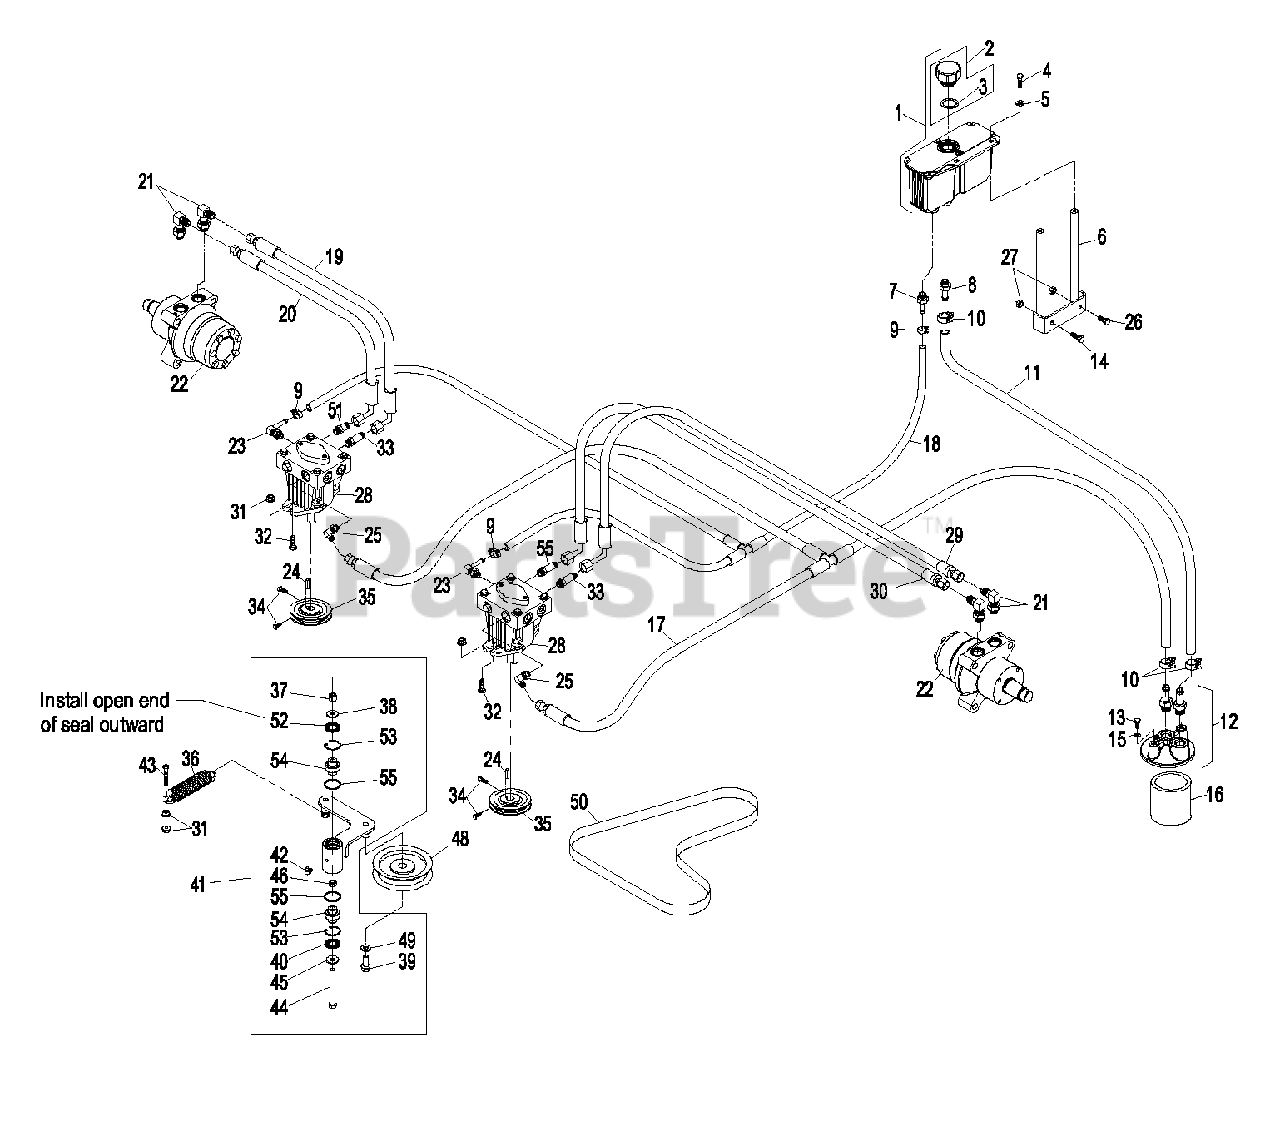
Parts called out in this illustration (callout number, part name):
1	HYD RESERVOIR ASM
2	KIT,HYD RES CAP W/GASKET
3	GASKET-CAP
4	SCREW-HH
5	WASHER-FLAT
6	STAND-RESERVOIR
7	ADAPTER-STRAIGHT
8	ADAPTER-STRAIGHT
9	CLAMP-HOSE
10	CLAMP-HOSE
11	HYD HOSE ASM
12	FILTER HEAD ASM
12	ADAPTER-STRAIGHT
13	SCREW-HH
14	SCREW-HH
15	WASHER-LOCK
16	FILTER-25 MICRON, BI-DIRE
16	ELEMENT-FILTER, WINTER
17	HYD HOSE ASM
18	HYD HOSE ASM
19	HOSE-REAR, RH
19	HOSE, HYDRAULIC
20	HOSE-REAR, RH
20	HOSE,HYDRAULIC
21	FITTING-HYD, 90 DEG
22	MOTOR-WHEEL
23	ELBOW-90 DEG
25	FITTING-ELBOW, 90 DEG
26	SCREW-HH
28	PUMP-HYD
28	INPUT SHAFT KIT
28	BEARING-THRUST
28	CYLINDER BLOCK KIT
28	SEAL OVERHAUL KIT
29	HOSE-REAR, LH
30	HOSE-REAR, RH
30	HOSE,HYDRAULIC
31	NUT-HHF, WHIZ
32	SCREW-HH
33	ADAPTER-STR, LONG
34	SCREW-SET
36	SPRING-EXTENSION
37	NUT-LOCK, NI
38	WASHER-BELLEVILLE
39	SCREW-HHF
40	SEAL-LIP, DOUBLE
41	KIT, PUMP IDLER LHP/LCT
42	FITTING-GREASE, 90 DEG
43	SCREW-HH
44	SCREW-HH
45	WASHER-FLAT
48	PULLEY-IDLER, FLAT
49	WASHER-FLAT
50	BELT
51	ADAPTER-STRAIGHT
52	SEAL-LIP, SINGLE
53	RING-SNAP
54	BEARING-SPHERICAL
55	ADAPTER-STR, LONG
